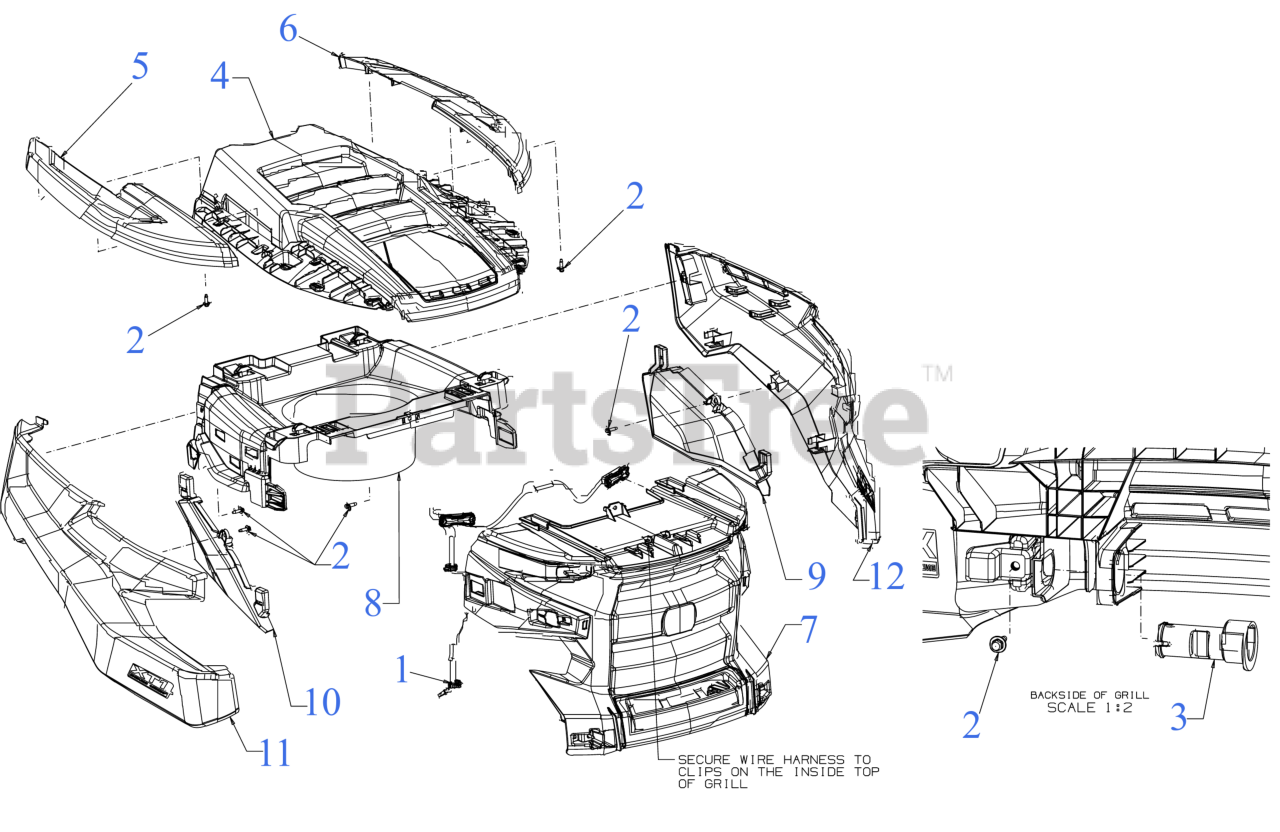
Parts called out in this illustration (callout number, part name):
1	HEADLIGHT HARNESS (W/LED)
2	SCREW 1/4-10 x .750
3	HOOD PIVOT PIN
4	HOOD (TOP)
5	HOOD (TOP) (RH)
6	HOOD (TOP) (LH)
7	GRILLE (FRONT) (T STYLE)
8	PLENUM/HOOD FRAME
9	PANEL (LOWER SIDE) (LH)
10	PANEL (LOWER SIDE) (RH)
11	PANEL (UPPER) (RH) (T STYLE)
12	PANEL (UPPER) (LH) (T STYLE)
